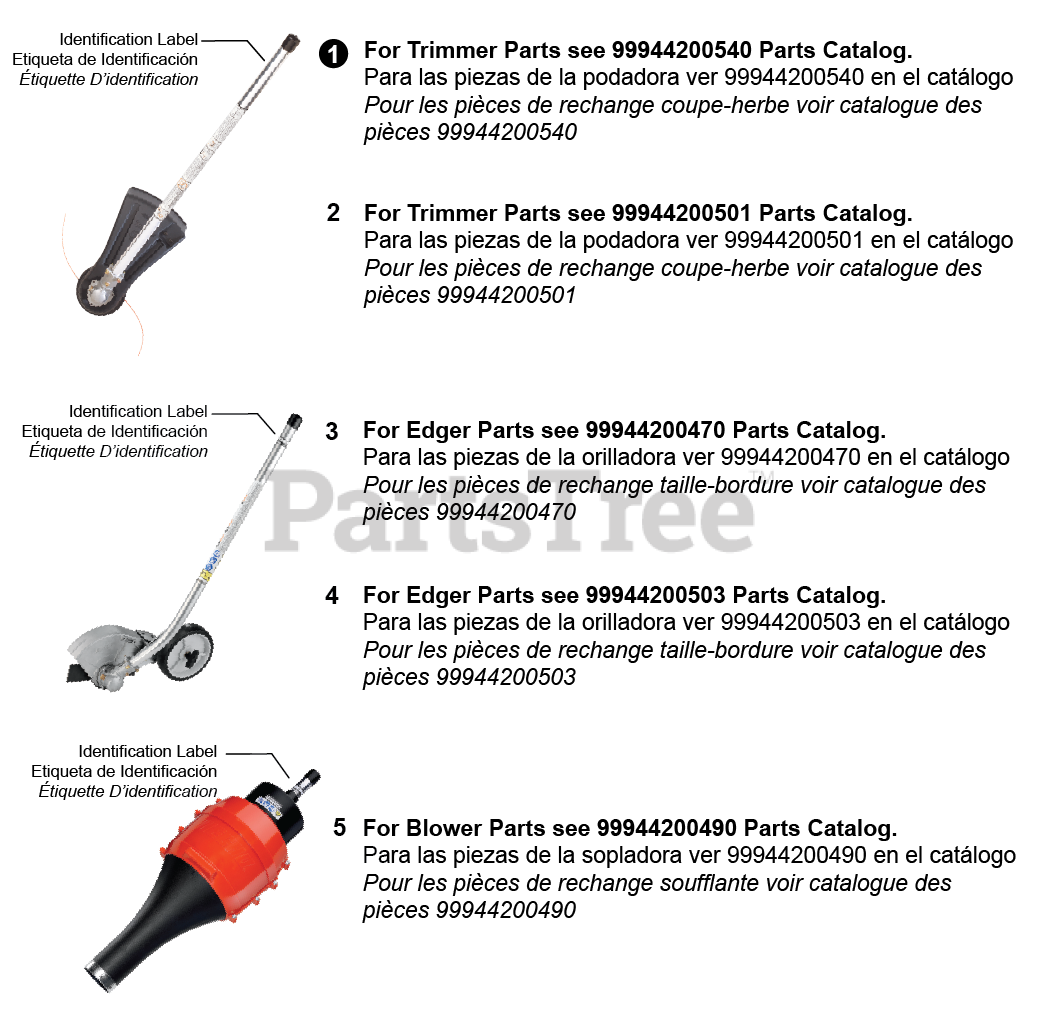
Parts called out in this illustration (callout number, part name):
1	TRIMMER ATTACHMENT
2	TRIMMER ATTACHMENT
3	EDGER ATTACHMENT
4	EDGER ATTACHMENT
5	BLOWER ATTACHMENT
